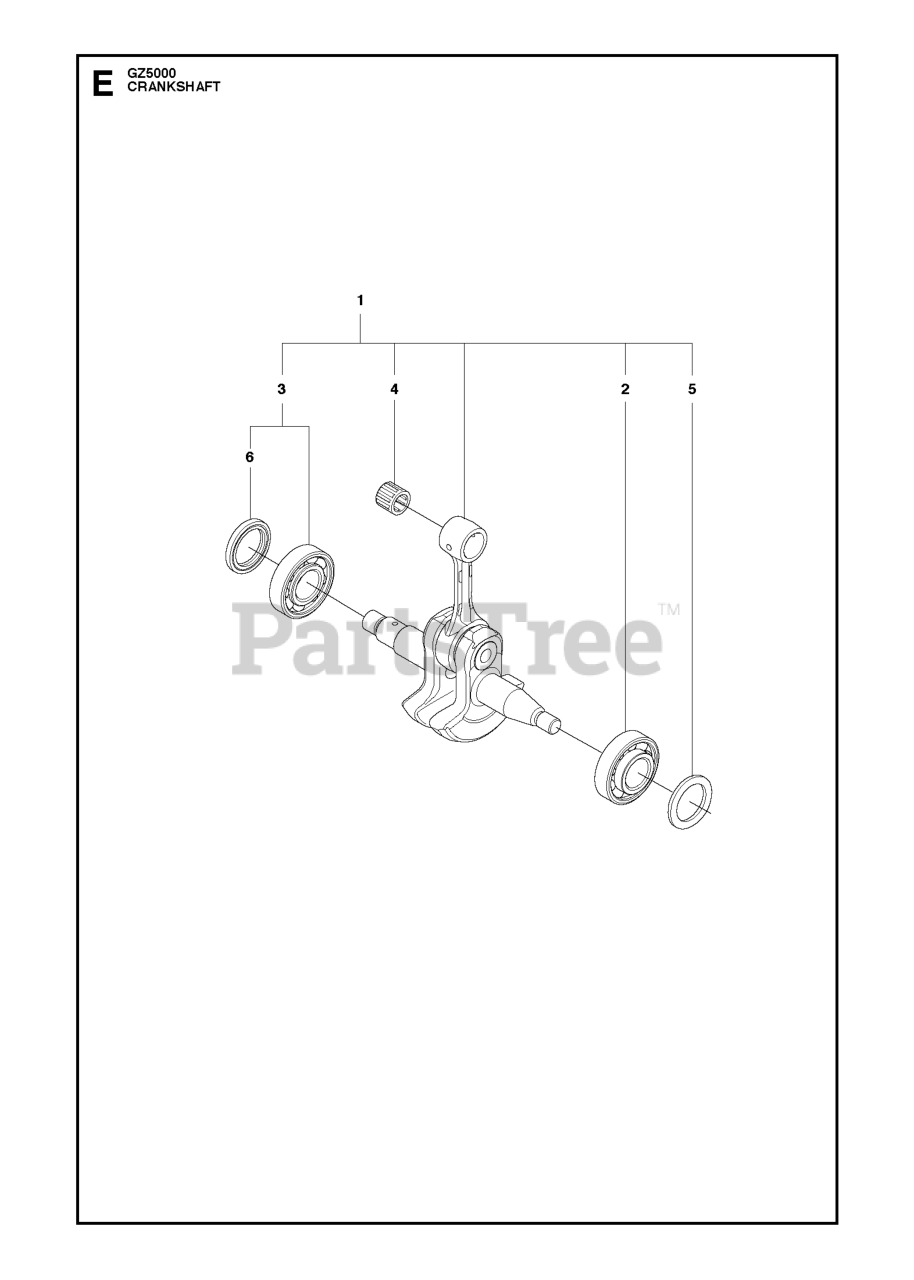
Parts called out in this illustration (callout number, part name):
1	CRANKSHAFT ASSY
2	BALL BEARING
3	BALL BEARING
4	SUPPORT BUSHING
5	RADIAL SEAL
6	RADIAL SEAL
